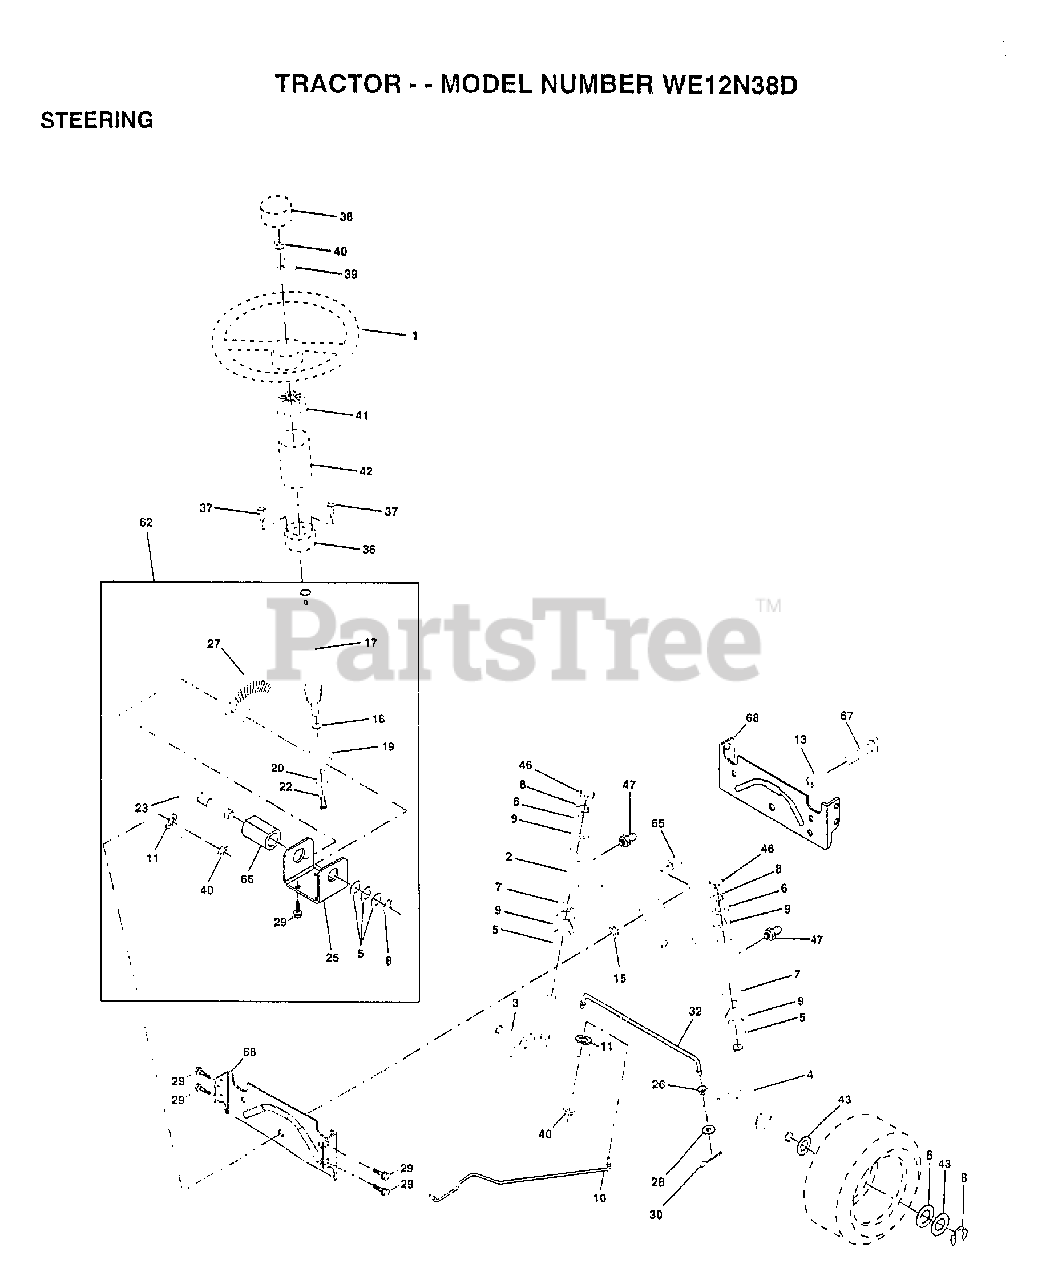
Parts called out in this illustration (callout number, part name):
2	AXLE ASM
3	SPINDLE.ASM.LH
4	"SPINDLE ASM,RH"
5	WASHER .T
6	WASHER
7	WASHER
8	RING
9	COL. SRTG. BEAR.
10	DRAGLINK-STAMPED
11	LOCKWASHER
13	BEARING AXLE
15	"NUT-LOC,FLANGE LT"
17	SHAFT ASSM STEERN
18	THRUST WASHER
19	SUPPORT.SHAFT
22	SCREW HEX SOC1/4-
25	BRKT-STEERING
26	BUSHING.DRAGLINK
27	GEAR SECTOR
28	WASHER
29	SCREW
30	COTTER PIN
32	TIE ROD
36	BUSHING.STEERING
37	"SCREW-TT,10-32 FL"
38	ST WHL INSERT CAP
39	WASHER T
40	GRIPCO NUT
41	ADAPTER-WHEEL LT
42	"TUBE, STR SHAFT"
43	WASHER
46	CAP
47	ZERK M
62	STEERING ASM KIT
65	SPACER AXLE
66	"BEARING-ARM,PITMA"
67	BOLT
68	BRACE AXLE
